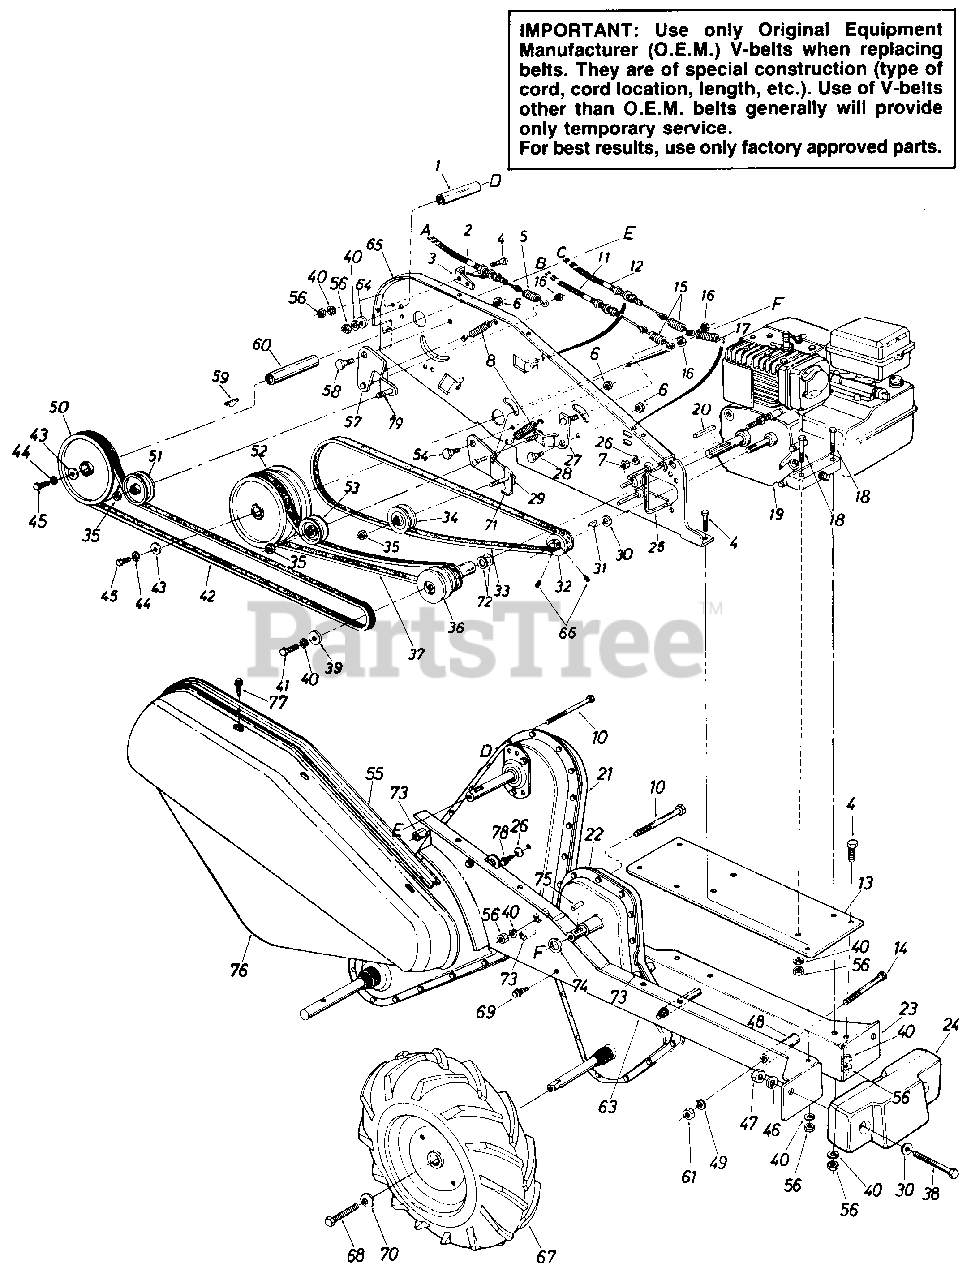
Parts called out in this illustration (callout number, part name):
1	Spacer .375" I.D. x .5" O.D. x 2" Lg.
2	Clutch Control Cable
3	Clutch Cable Bracket
4	Hex Bolt 5/16-18 x .75" Lg.
5	Extension Spring .50" O.D. x 2.5" Lg.
6	Hex Cent. L-Nut 3/8-16 Thd.
7	Hex Nut 1/4-20 Thd.
8	Extension Spring .50" O.D. x 1.55" Lg.
10	Hex Bolt 5/16-18 x 3" Lg.
11	Clutch Control Cable 42" Lg.
12	Clutch Control Cable 42" Lg.
15	Springs
16	Hex Cent. L-Nut 1/4-20 Thd.
17	Extension Spring .41" O.D. x 2.05" Lg.
18	Hex Bolt 5/16-18 x 1.5" Lg.
19	Engine
20	Sq. Key 3/16 x 1.00" Lg.
21	Chain Case Comp.-Tines
22	Chain Case Comp.-Wheels
25	Belt Keeper
26	Bell-Wash. .265" I.D. x .75" O.D.
29	Idler Brkt. Ass'y.
30	Fl-Wash. .51" I.D. x 1.0"
31	#5 Hi-Pro-Key 1/8" x 5/8" Dia.
32	1/2" V-Pulley 2.25" O.D. x 503a I.D.
33	"V"-Belt
34	"V"-Belt Idler 2.62" O.D.
35	Hex Ins. L-Nut 3/8-24 Thd.
36	1/2" "V"-Pulley Ass'y.
37	"V"-Belt
38	Hex Bolt 1/2-13 x 4" Lg.
39	Fl-Wash. .344" I.D. x 1.125"
40	L-Wash. 5/16" I.D.
41	Hex Bolt 5/16-24 x 1.00" Lg.
42	"V"-Belt
43	Fl-Wash. 1/4" I.D. x .93" O.D.
44	L-Wash. 1/4" I.D.
45	Hex Bolt 1/4-28 x .75" Lg.
46	L-Wash. 1/2" I.D.
47	Hex Nut 1/2-13 Thd.
48	Spacer .38" I.D. x .62" O.D. x 2.18" Lg.
49	L-Wash. 3/8" I.D.
50	Fl-Pulley w/Flanges 6" O.D.
51	Fl-Idler w/Flanges 3.75" O.D.
52	Double Fl-Pulley 5/8" I.D.
53	Fl-Idler w/Flanges 2.12" O.D.
54	Shld. Bolt .500" Dia. x .170" Lg.
55	Flange Extension
56	Hex Nut 5/16-18 Thd.
59	#61 Hi-Pro-Key 3/16" x 5/8" Dia.
60	Spacer ,647" I.D. x 2.75" Lg.
61	Hex Nut 3/8-24 Thd.
65	Side Plate Ass'y.
66	Set Scr. 1/4-28 x .25" Lg.
67	R.H. Wheel Ass'y. Comp. 13 x 5
68	Hex Bolt 5/16-24 x .62" Lg.
69	Hex Self-Tap Scr. 5/16-24 x .5" Lg.
70	Bell-Wash. 5/16" I.D.
71	Belt Keeper Brkt.
72	Fl-Wash. .76" I.D. x l.5"
73	Spacer .326" I.D. x ,47" O.D. x .96" Lg.
74	Fl-Wash. .635" I.D. x 1" O.D.
75	Sq. Key 3/16 x ,75n Lg.
78	Hex Wash. S-Tap Scr. 1/4-20 x .38" Lg.
79	Hex Bolt 3/8-24 x 1.25" Lg.
